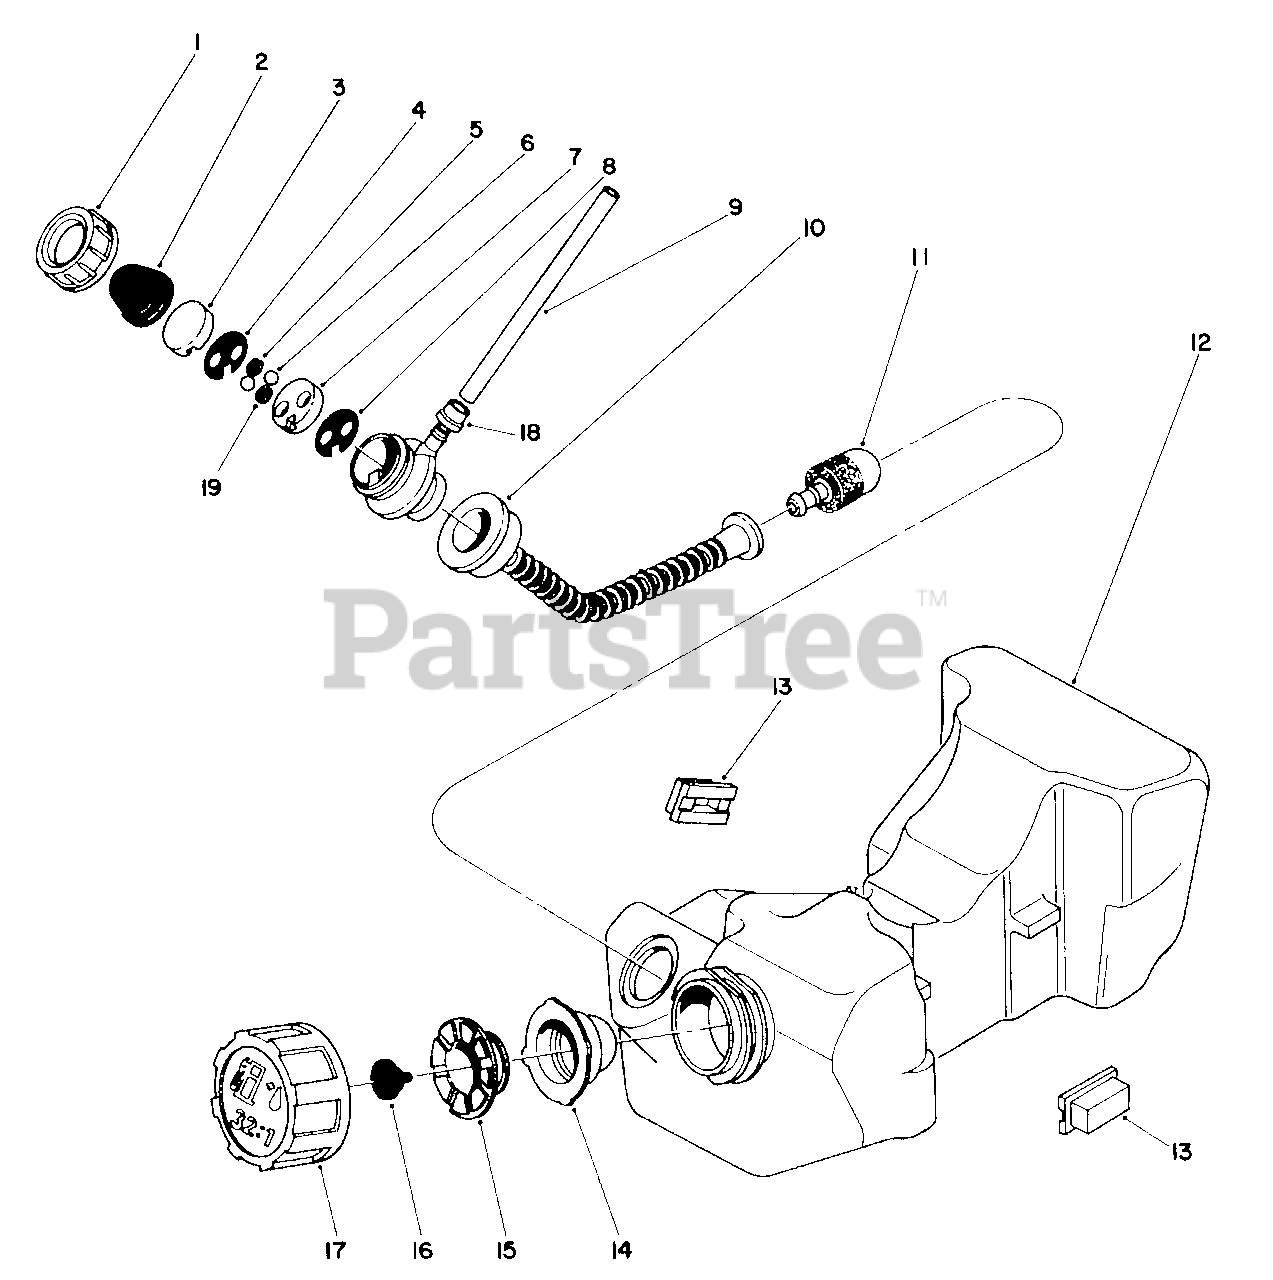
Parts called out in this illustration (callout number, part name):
1	Nut, Cap
3	Seat, Valve
7	Seat, Valve
9	Tube, Fuel
10	Hose, Suction
11	Filter, Fuel
12	Fuel Tank Assembly (Incl. Ref. #1-8, 10, 11, 14-17 & 19)
16	Valve, Breather
17	Cap, Tank
19	Cushion Ball
